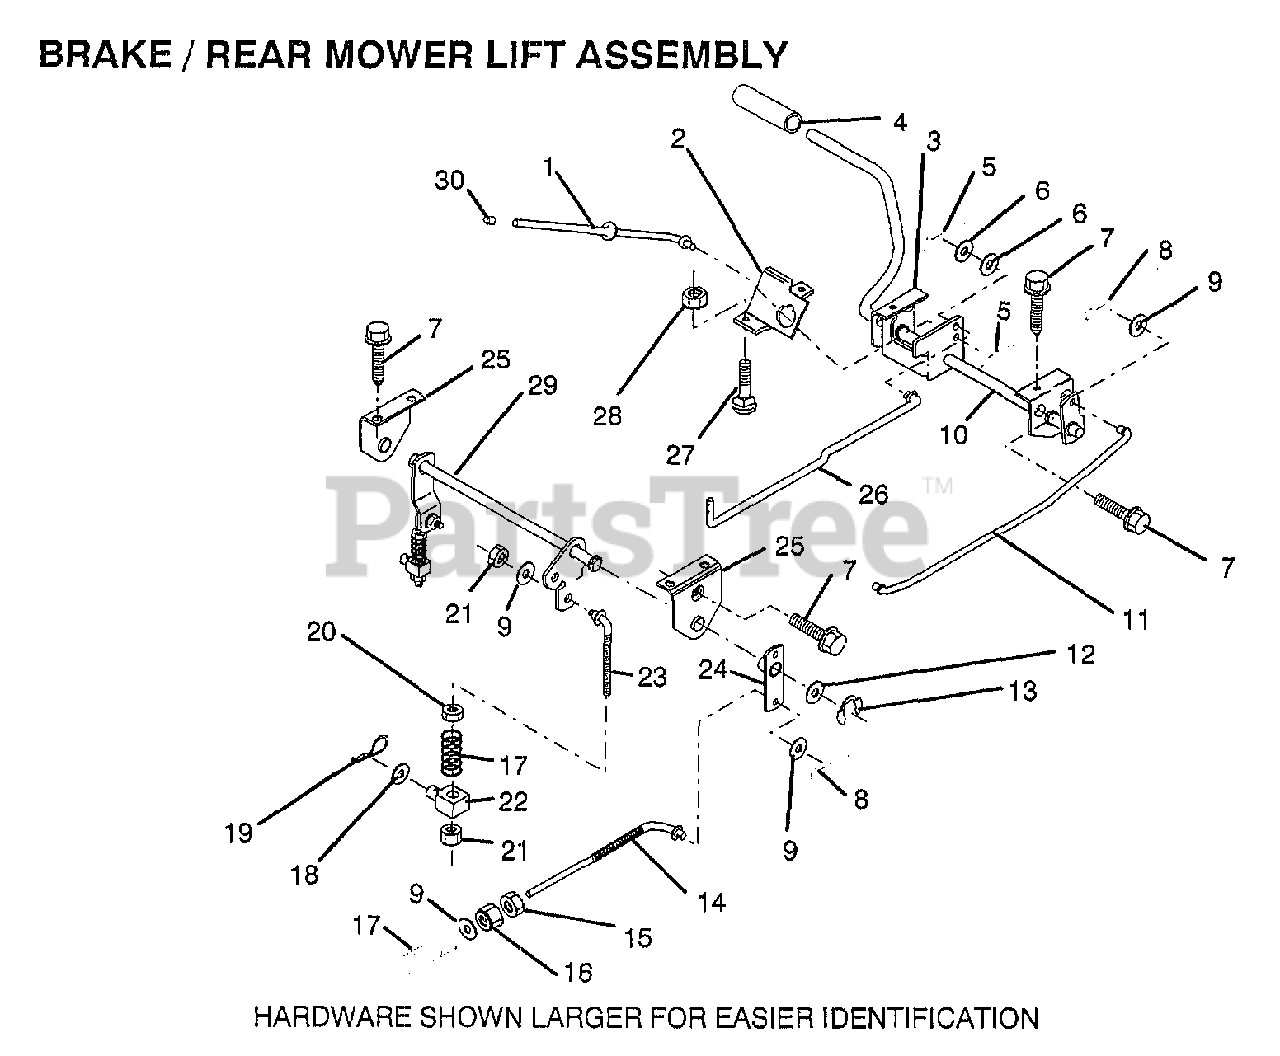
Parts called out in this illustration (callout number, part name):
1	"ROD,PARK BRAKE"
2	"BRKT,PARK BRAKE"
3	"BRKT,CLU PEDAL LH"
4	PEDAL COVER T
6	WASHER
7	SCREW LT
8	COTTER PIN
9	WASHER
11	"ROD,FRT BRAKE"
12	WASHER T
13	KLIP RING
15	NUT
16	NUT
17	SPRING ROD LT
18	WASHER
19	SPRING.RETAINER
20	LOCKNUT
23	"LINK.LIFT.3.5"""
24	BRAKE PIVOT ARM
25	"BRKT,LIFT SHAFT"
26	"ROD,CLUTCH"
29	REAR MOWER LIFT
30	PLUNGER CAP T
